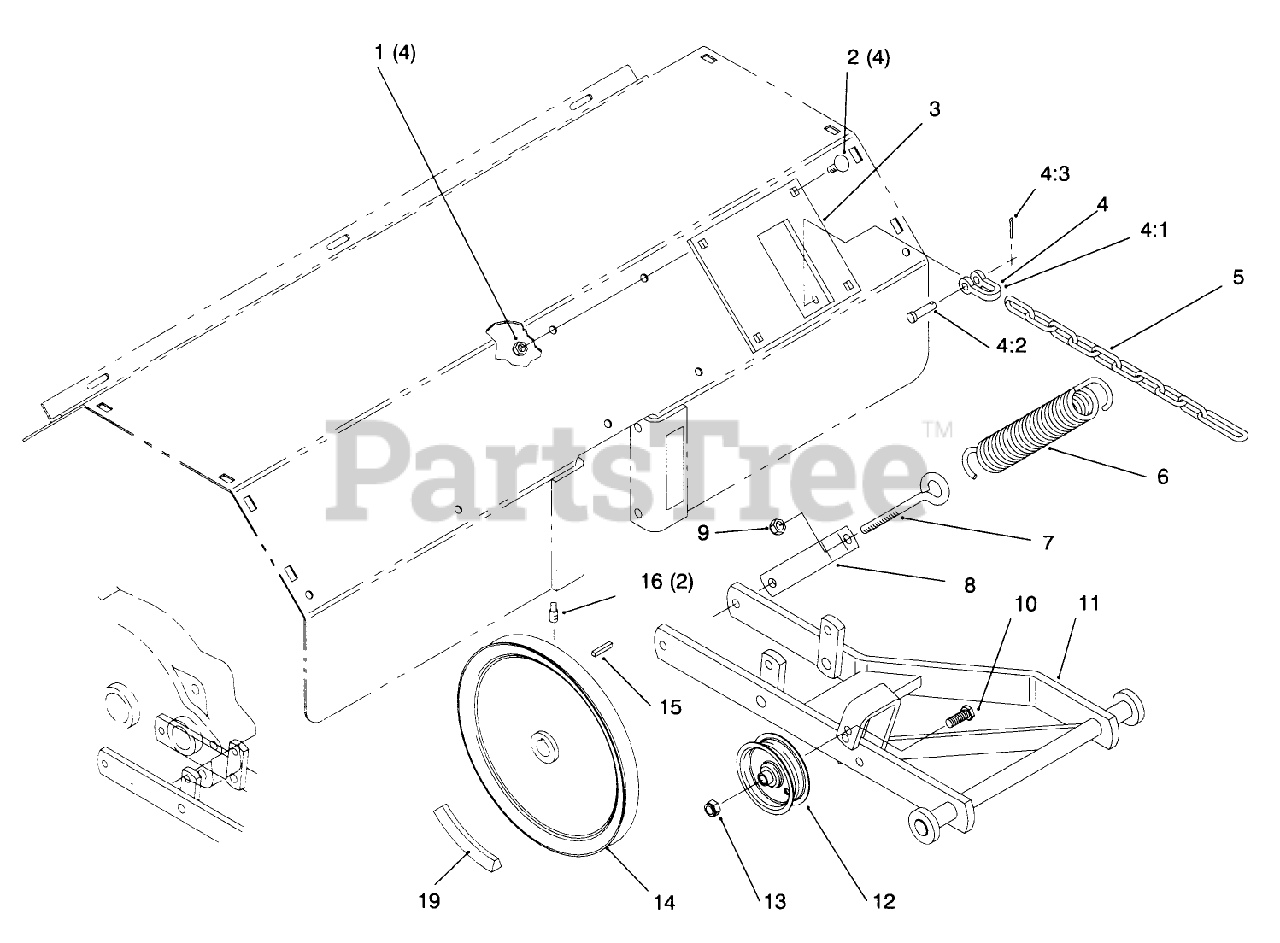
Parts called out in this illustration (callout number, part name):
1	NUT-LOCK, NI
2	BOLT-CARR
3	HITCH ASM
4	CLEVIS ASM
5	CHAIN LIFT
6	SPRING
7	EYEBOLT
8	BRACKET - SPRING RED
9	NUT-LOCK, NI
10	HEX HD CAP SCREW
11	HITCH ASM RED
12	PULLEY-IDLER
13	NUT-HEX
14	PULLEY
15	KEY-STRAIGHT
16	SCREW-SQH
19	V-BELT
